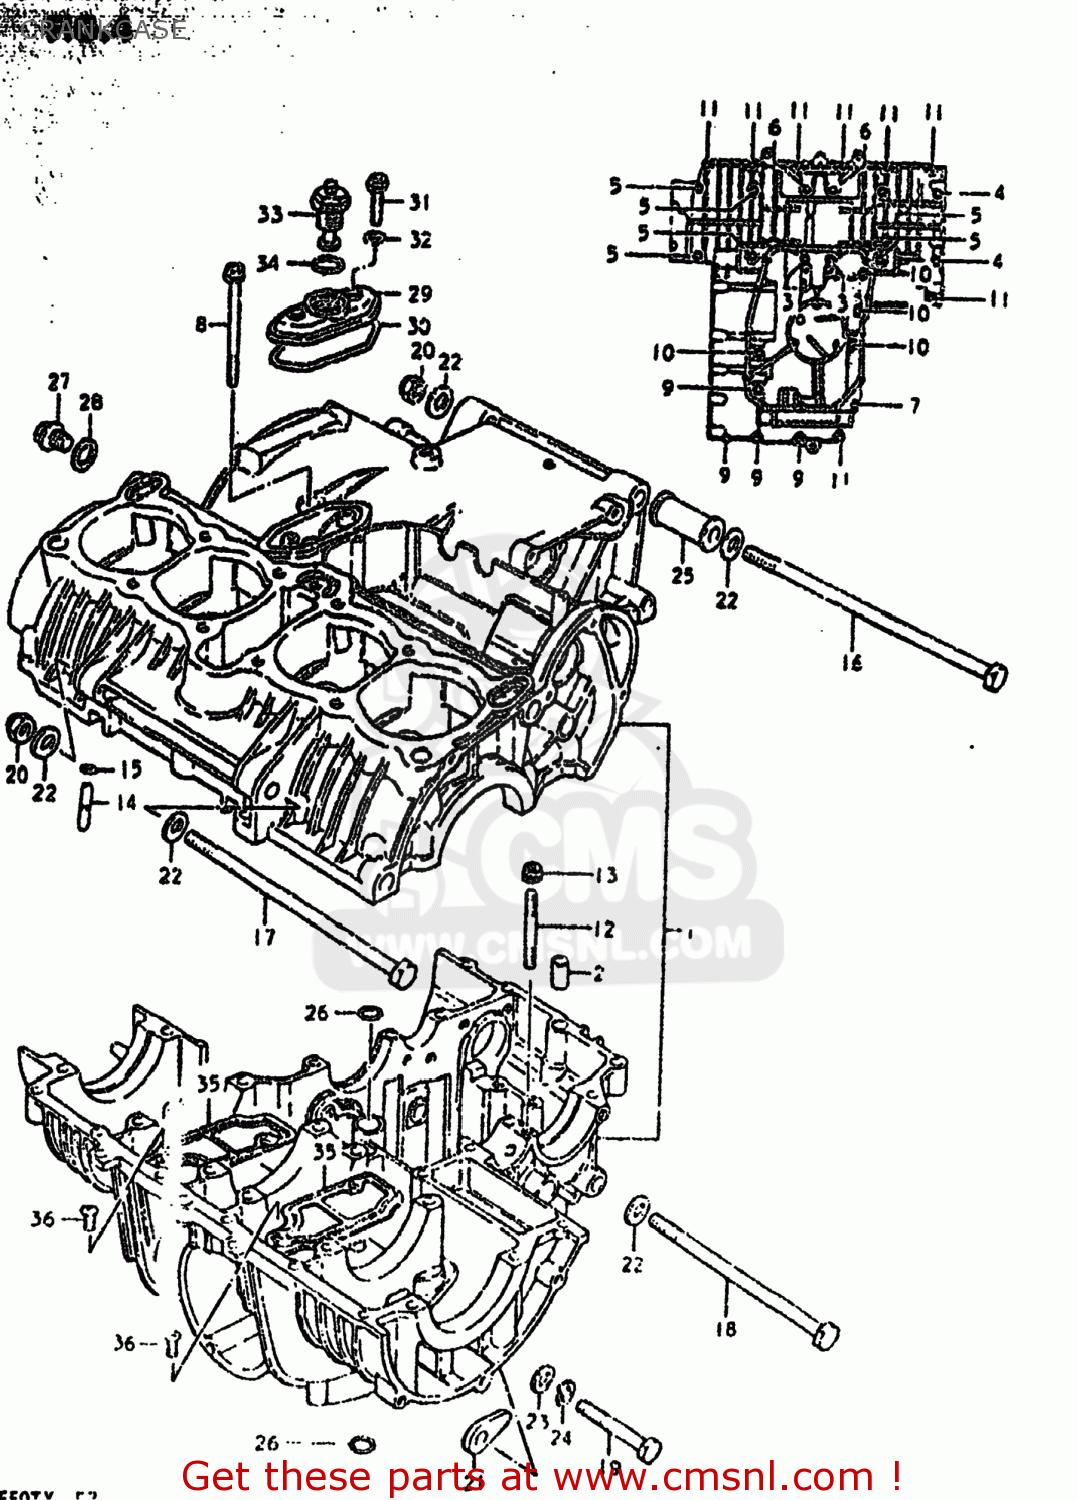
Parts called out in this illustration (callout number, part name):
1	CRANKCASE SET
2	PIN
3	BOLT
4	BOLT 8X90
5	BOLT (8X70)
6	BOLT 8X55
7	BOLT (8X45)
8	BOLT (6X90)
9	BOLT (6X60)
10	BOLT ,6X50
11	BOLT
12	STUD BOLT
13	NUT
14	UNION
15	O RING(D:1.05,ID:3.1)
16	BOLT 10X270
17	BOLT
18	BOLT
19	BOLT 10X55
20	NUT
21	NUT
22	WASHER
23	WASHER(10.5X20X3.2)
24	LOCK WASHER
25	SPACER,ENGINE MOUNT
26	O RING(D:3.2,ID:12.9)
27	PLUG (14X12)
28	GASKET(14X19.2X2) (NAS)
29	HOUSING,OIL PRESSURE SWITCH
30	O RING,PRESSURE SWITCH HOUSING
31	BOLT
32	GASKET (NAS)
33	SWITCH ASSEMBLY
34	O RING(D:1.9,ID:18.8)
35	PLATE,OIL SEPARATOR
36	SCREW
